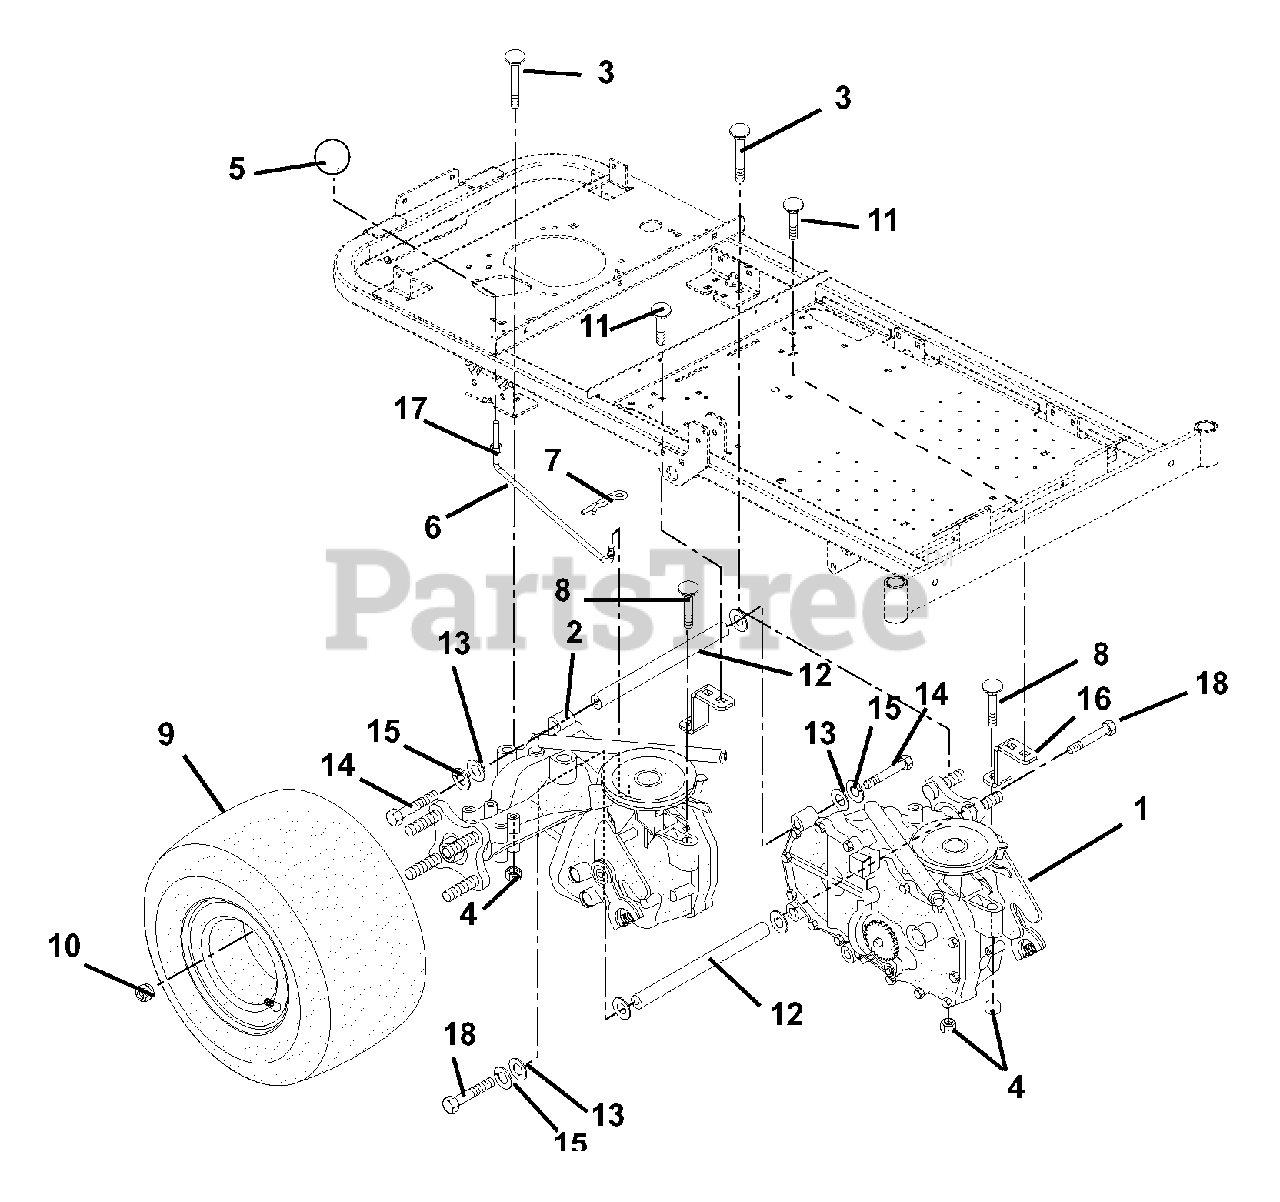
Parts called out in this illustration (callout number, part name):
1	EZT,LH TRANSAXLE-HYDROGEAR
2	EZT,RH TRANSAXLE-HYDROGEAR
3	BLT-RDHDSQSHNK.31-18X2.75G2YWZ
4	@NUT-LK-NYL-FLG .31-18 YWZC
6	ROD, DUMP EZT
7	PIN-HAIR, ENDRIES #25 YWZC
8	@BLT-RDHDSQNK .31-18X2.25 G5YZ
9	ASSY-TIRE 8.5X18 2PLY
10	NUT-LUG .50-20 YWZC
11	@BLT-RDHDSQNK .31-18X1.00 G5YZ
13	@WSHR-FL-STL.344X.688X.065YWZC
14	@BLT-HEX .31-18X2.50 GR5 YWZC
15	@WSHR-LK .31X.078 REG YWZC
16	TORQUE STRAP
17	@NUT-HEX .25-20 YWZC
18	@BLT-HEX .31-18X2.00 GR5 YWZC
